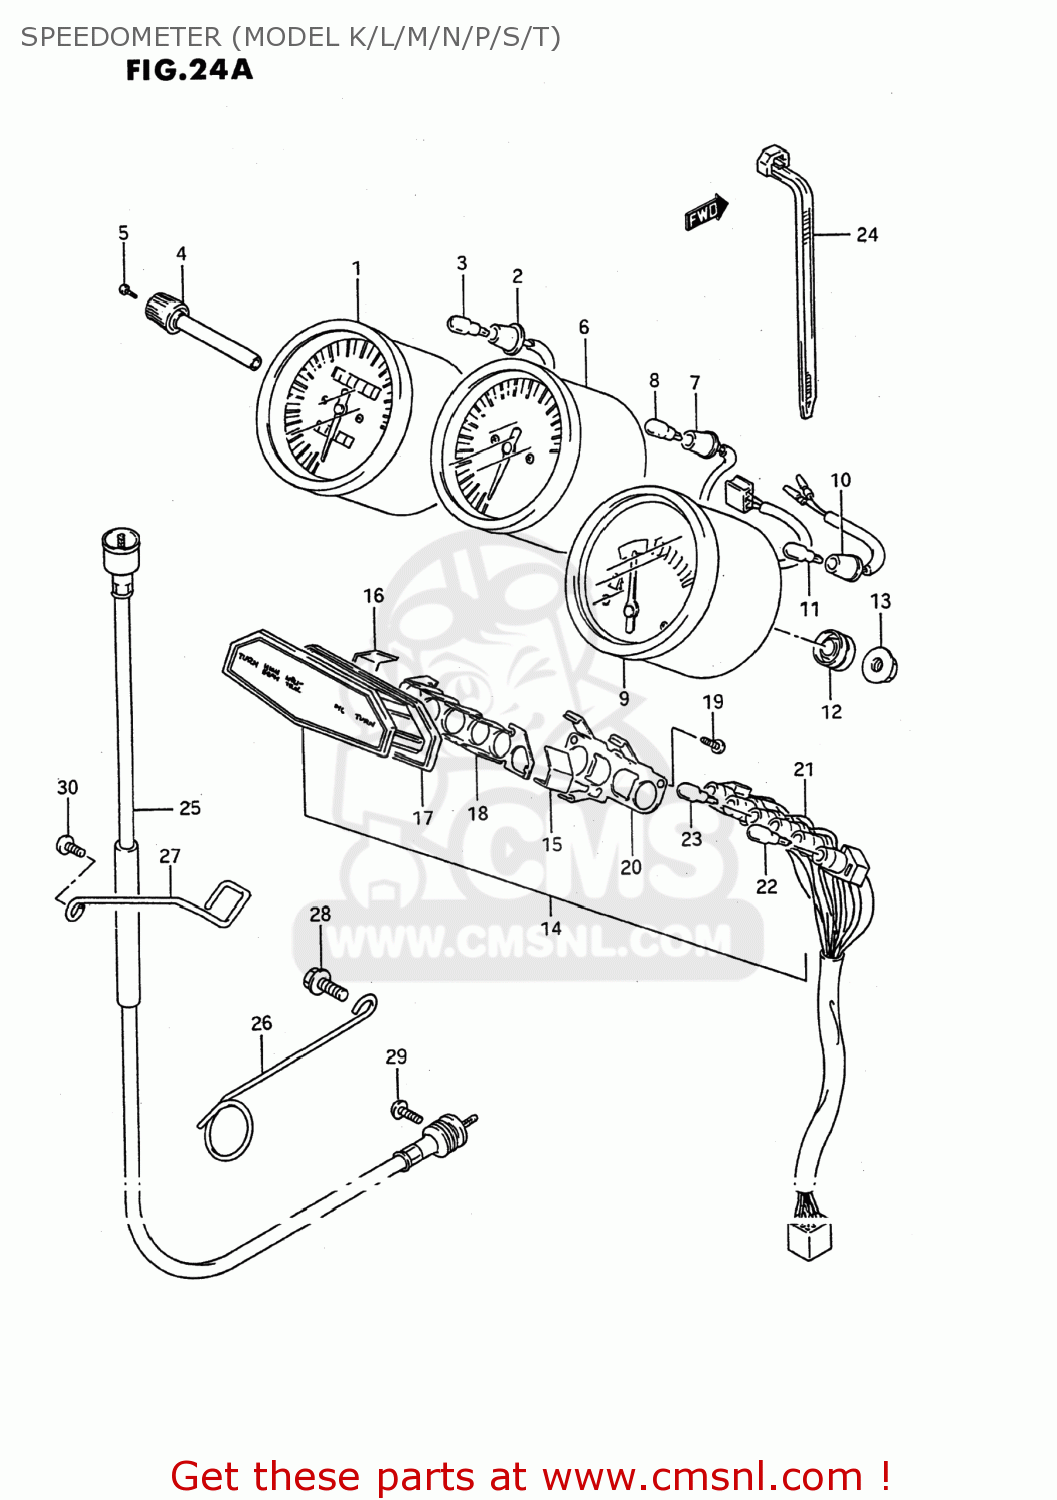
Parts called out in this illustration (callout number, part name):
1	SPEEDOMETER ASSY
2	SOCKET
3	BULB(12V3W,WB371,T7)
4	KNOB,TRIP
5	SCREW,TRIP KNOB
6	TACHOMETER ASSY
7	SOCKET
8	BULB(12V3W,WB371,T7)
9	METER ASSEMBLY,FUEL
10	SOCKET
11	BULB(12V3W,WB371,T7)
12	CUSHION
13	NUT
14	BOX ASSY
15	PLATE,TURN,R
16	PLATE,TURN,L
17	CUSHION
18	PLATE,PILOT LAMP
19	SCREW
20	LOCK PLATE
21	SOCKET
22	BULB(12V1.7W,WB372,T7)
23	BULB(12V3W,WB371,T7)
24	CLAMP(L:125)
25	CABLE ASSY,SPEEDOMETER
26	CLAMP,SPEEDOMETER CABLE
27	CLAMP,SPEEDOMETER CABLE
28	BOLT
29	SCREW
30	SCREW 5X12
